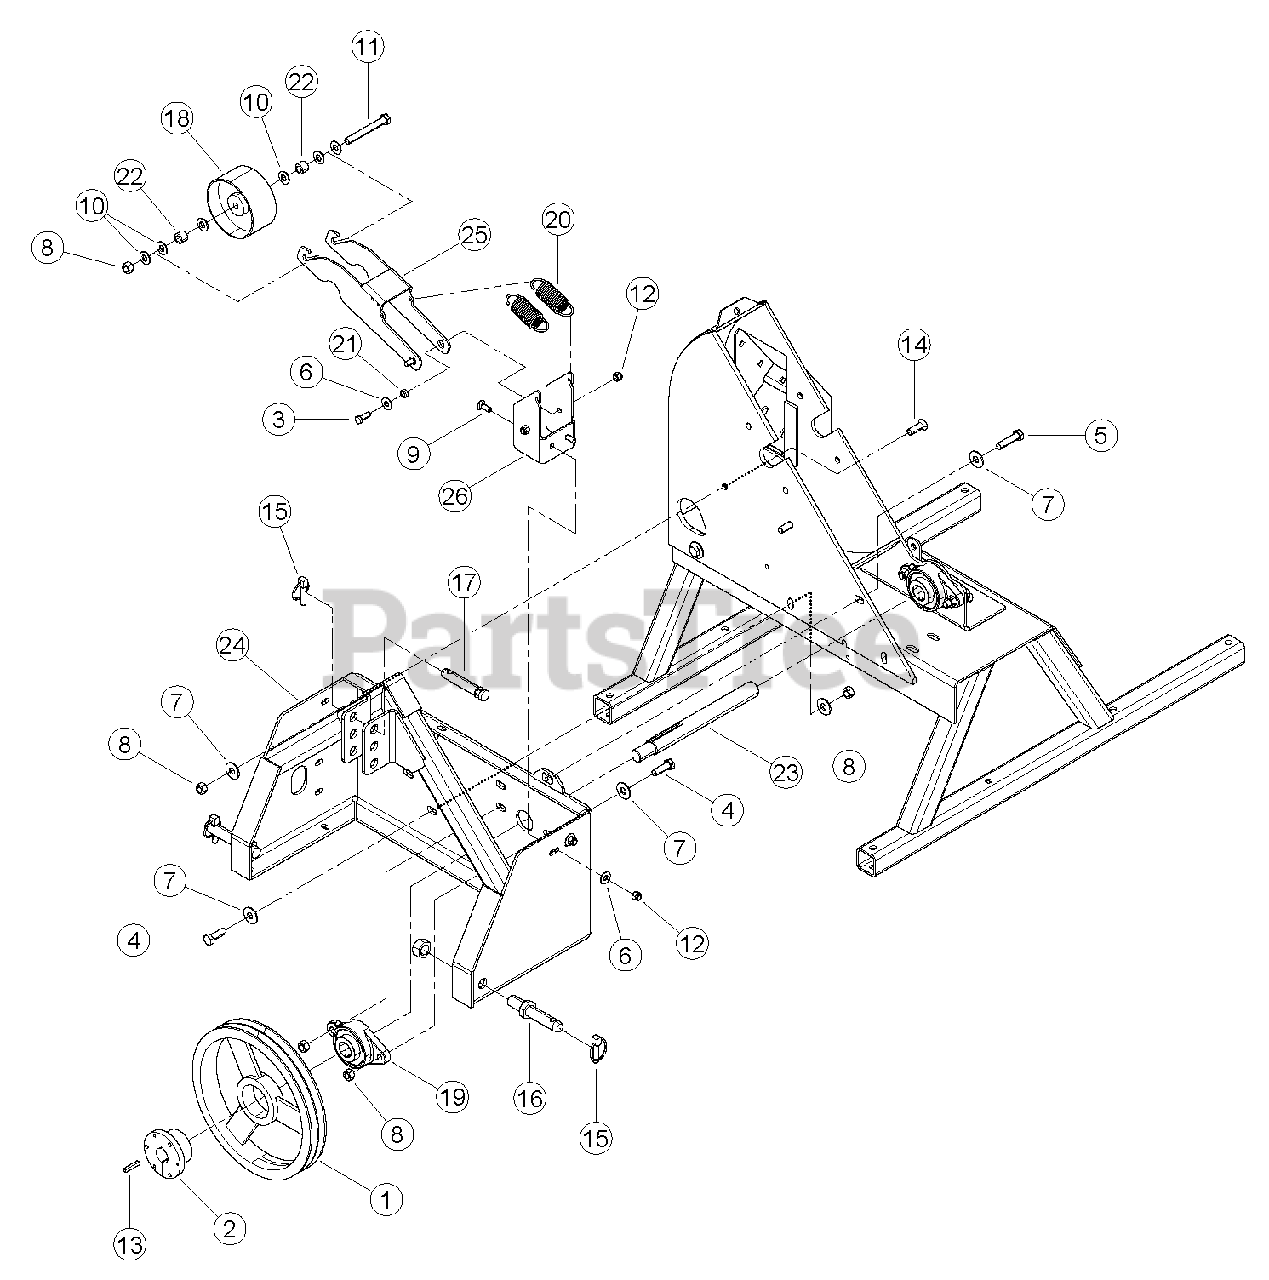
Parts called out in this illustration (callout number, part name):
1	SHEAVE, 2B 12.4" SK
2	BUSHING, SK 1-1/4"
3	BOLT, 3/8 X 1 HEX HD GR5 ZP
4	BOLT, 1/2 X 1-1/2 HEX HD GR5 ZP
5	BOLT, 1/2 X 2 HEX HD GR5 ZP
6	WASHER, 3/8 FLAT ZP
7	WASHER, 1/2 FLAT ZP
8	NUT, 1/2 CENTERLOCK GRB ZP
9	BOLT, 3/8 X 1 CRG GR5 NC ZP
10	WASHER, 1/2 SAE FLAT ZP
11	BOLT, 1/2 X 4 HEX HD GR5 ZP
12	NUT, 3/8 NE NYLOCK ZP
13	KEY, 1/4 SQUARE X 1-1/2 LONG PLAIN
14	SCREW, 1/2 X 1-1/2 FLT HD SKT
15	PIN, 7/16 X 1-3/4 LYNCH
16	PIN, LIFT ARM 7/8 X 5" LONG
17	PIN, TOP LINK 3/4 X 4-1/2" LONG
18	PULLEY, IDLER 5" X 2.50"
19	BEARING, 1-1/4" DIA. 2 BOLT FLANGE
20	SPRING, 1.25 OD X 3.50 LG X .148 WD
21	SPACER, IDLER PIVOT
22	SPACER, .81 X .620
23	JACKSHAFT, PTO CHIPPER
24	WELDMENT, CHIPPER HITCH
25	ARM, INSIDE IDLER
26	BRACKET, INSIDE IDLER ARM MOUNTING
